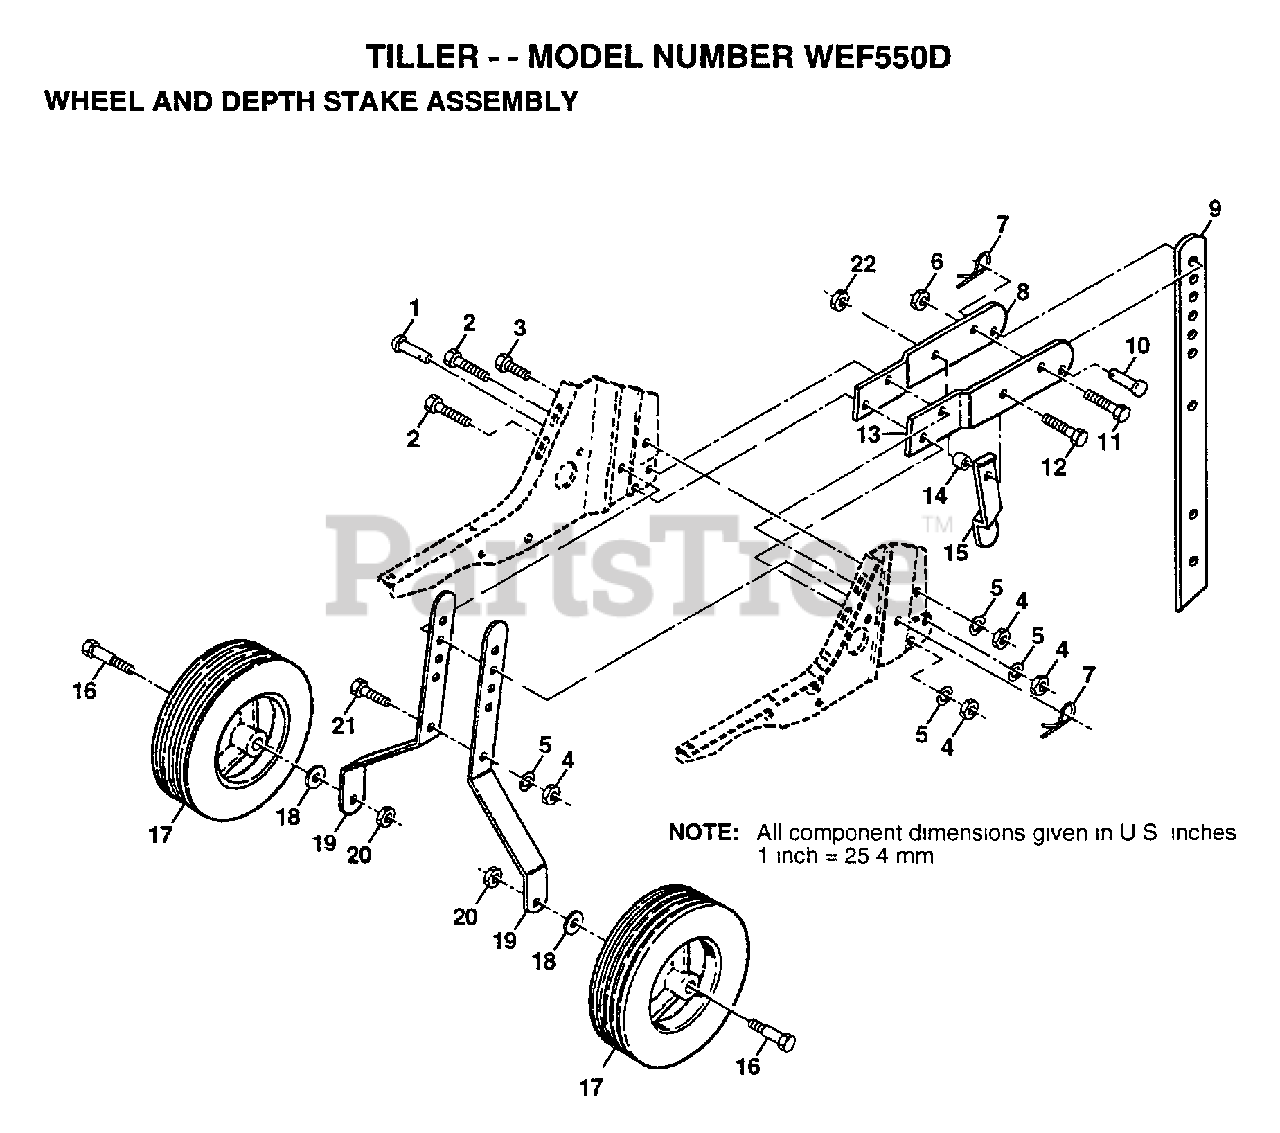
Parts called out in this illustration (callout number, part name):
1	DRILLED RIVET RT
3	BOLT
4	NUT.HEX.5/16-18
5	LOCKWASHER
6	NUT
7	SPRING.RETAINER
8	SUPPORT STAKE RH
11	BOLT
12	BOLT.HEX.5/16-1.5
13	SUPPORT STAKE LH
14	WASHER
15	STAKE SPRING TI
16	BOLT SHOULDER
17	WHEEL.8X1.75.YELL
18	WASHER
19	BRACKET.WHL.PNT.
22	NUT
